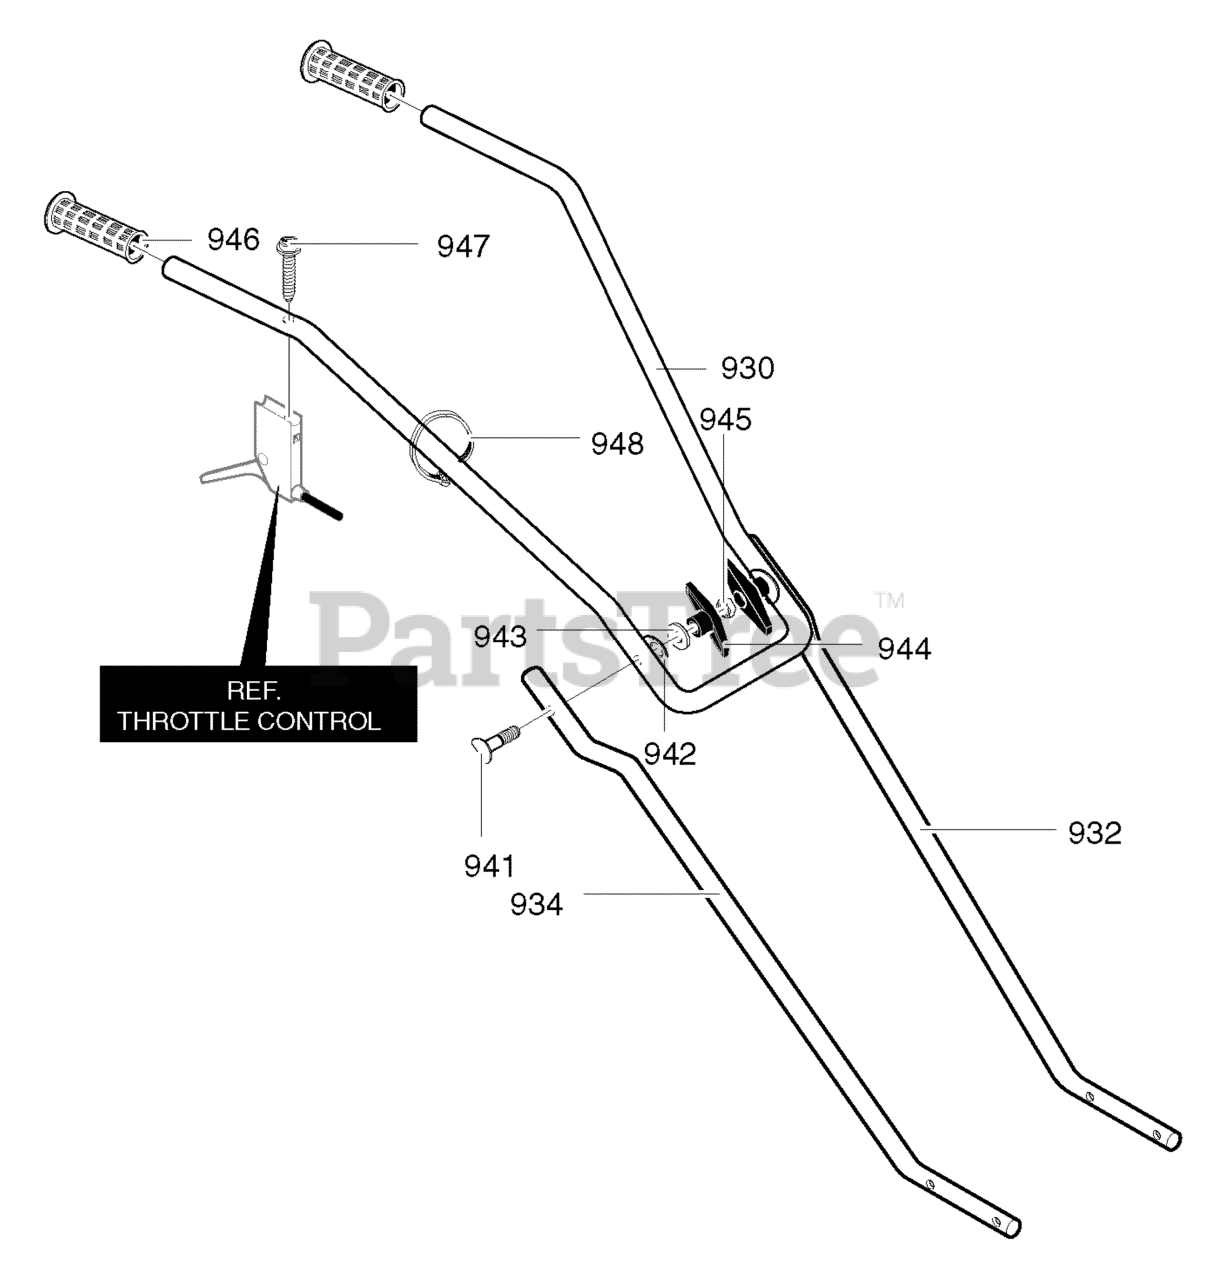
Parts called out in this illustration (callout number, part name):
930	HANDLE, Upper
932	HANDLE, Lower LH
934	HANDLE, Lower RH
941	BOLT 5/16-18x1.63
942	WASHER, Formed
943	FLATWASHER
945	NUT, 5/16-18
948	TIE, Cable
